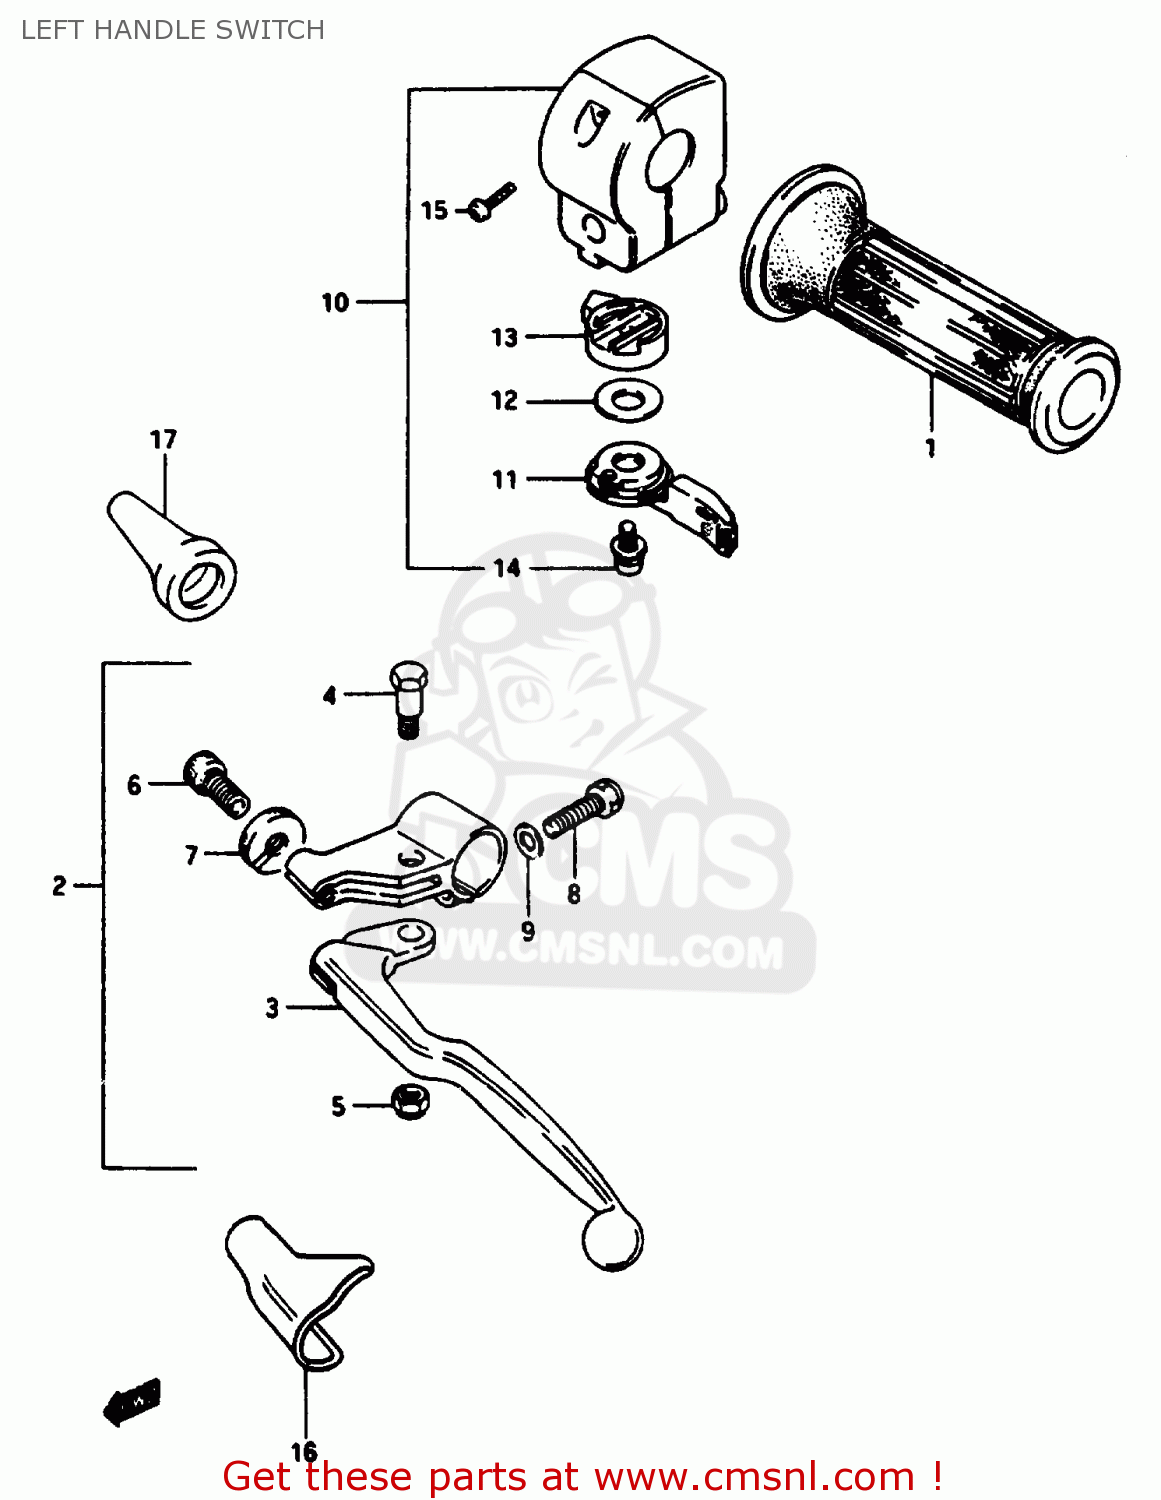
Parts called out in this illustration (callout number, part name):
1	GRIP,L
2	LEVER ASSY, CLUTCH
3	LEVER,CLUTCH
4	BOLT,LEVER PIVOT
5	NUT
6	ADJUSTER,CABLE
7	NUT,CABLE ADJUSTER LOCK
8	BOLT
9	WASHER
10	SWITCH ASSY, HANDLE LH
11	LEVER,STARTER
12	WASHER,ADJUSTER
13	BODY,STARTER LEVER
14	SCREW,CHOKE LE
15	SCREW
16	COVER,CLUTCH LEVER
17	BOOT,CLUTCH CABLE
